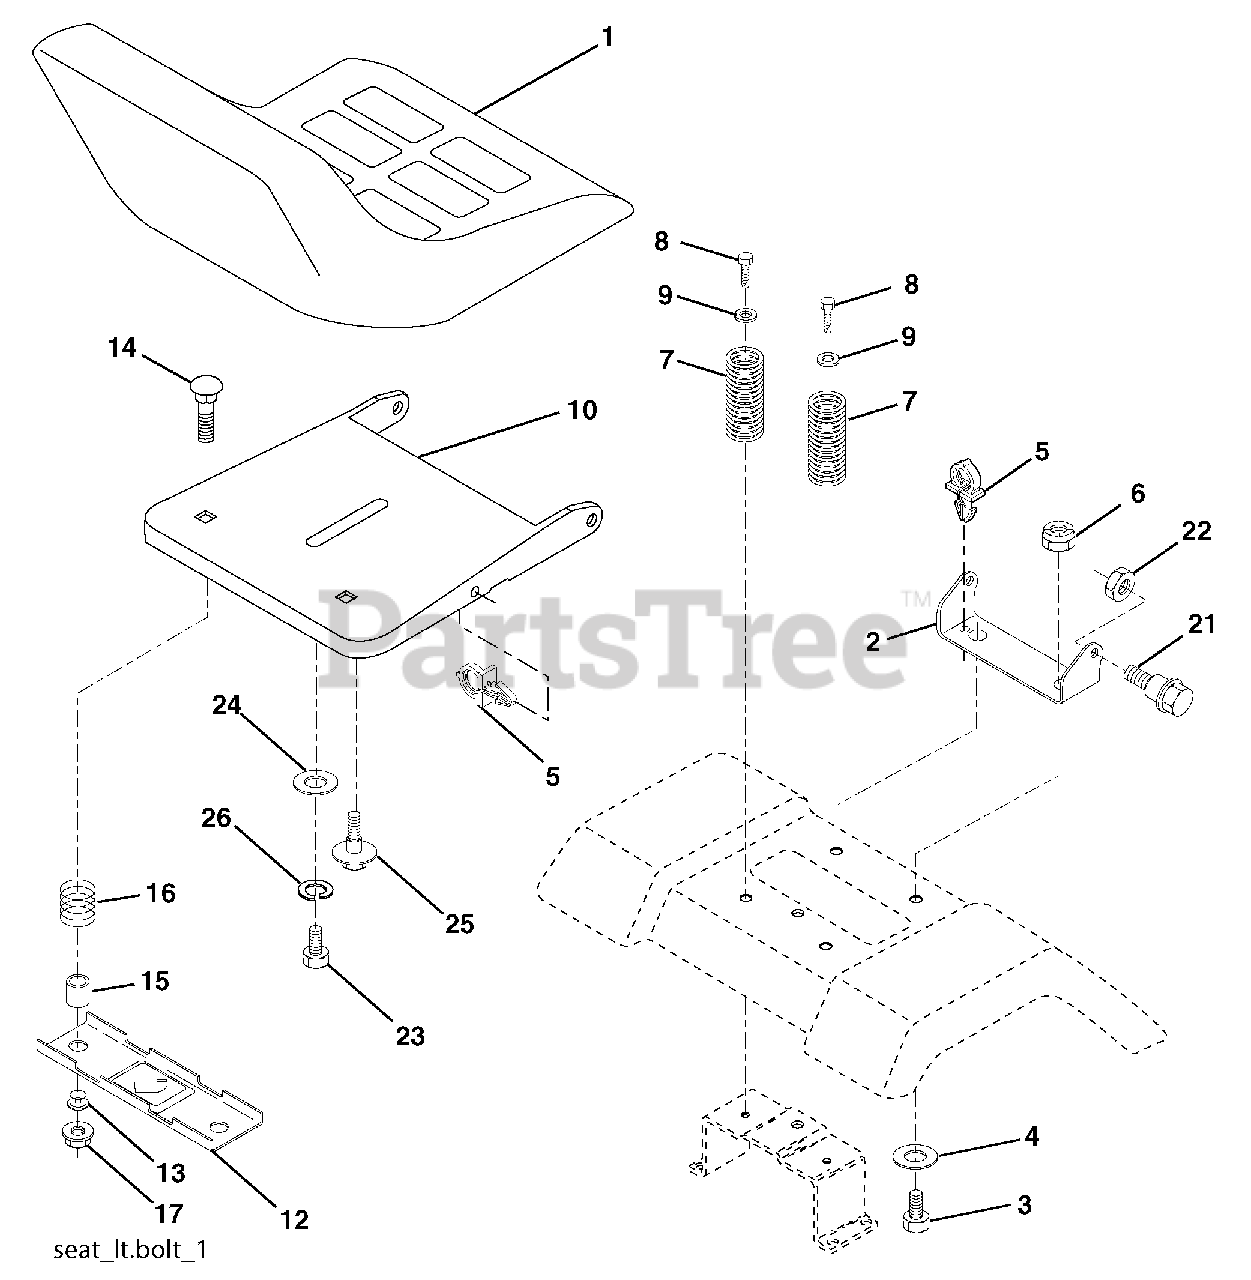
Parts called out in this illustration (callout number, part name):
1	Seat
2	Bracket Seat Pivot
3	Bolt Hex 3/8 - 16 x 1
4	Washer 13/32 x 1 x10 Ga.
5	Clip Push-In Hinged
6	Nut Lock Hex w/Ins 3/8 - 16
7	Spring Seat Cprsn 2 250 Blk Zi
8	Screw 3/8-16 x 1.5
9	Washer 13/32 x 1 x 14 Ga.
10	Pan Pnt Seat (Blk)
12	Bracket Pnt Mounting Switch
13	Bushing Snap Blk Nyl
14	Bolt Rdhd Sht Nk 1/4 - 20 x 1 -1/2
15	Spacer Split .28 x .96
16	Spring Cprsn
17	Nut Lock 1/4 Lge Flg
21	Bolt Shoul der 5/16-18 unc-2A
22	Nut Lock Hex w/Ins 5/16 - 18
23	Bolt Hex
24	Washer 17/32 x 1-3/16 x 12 Ga.
25	Bolt Shoul der 5/16-18 x .62
26	Washer Lock Hvy Hlcl Spr 1/2
